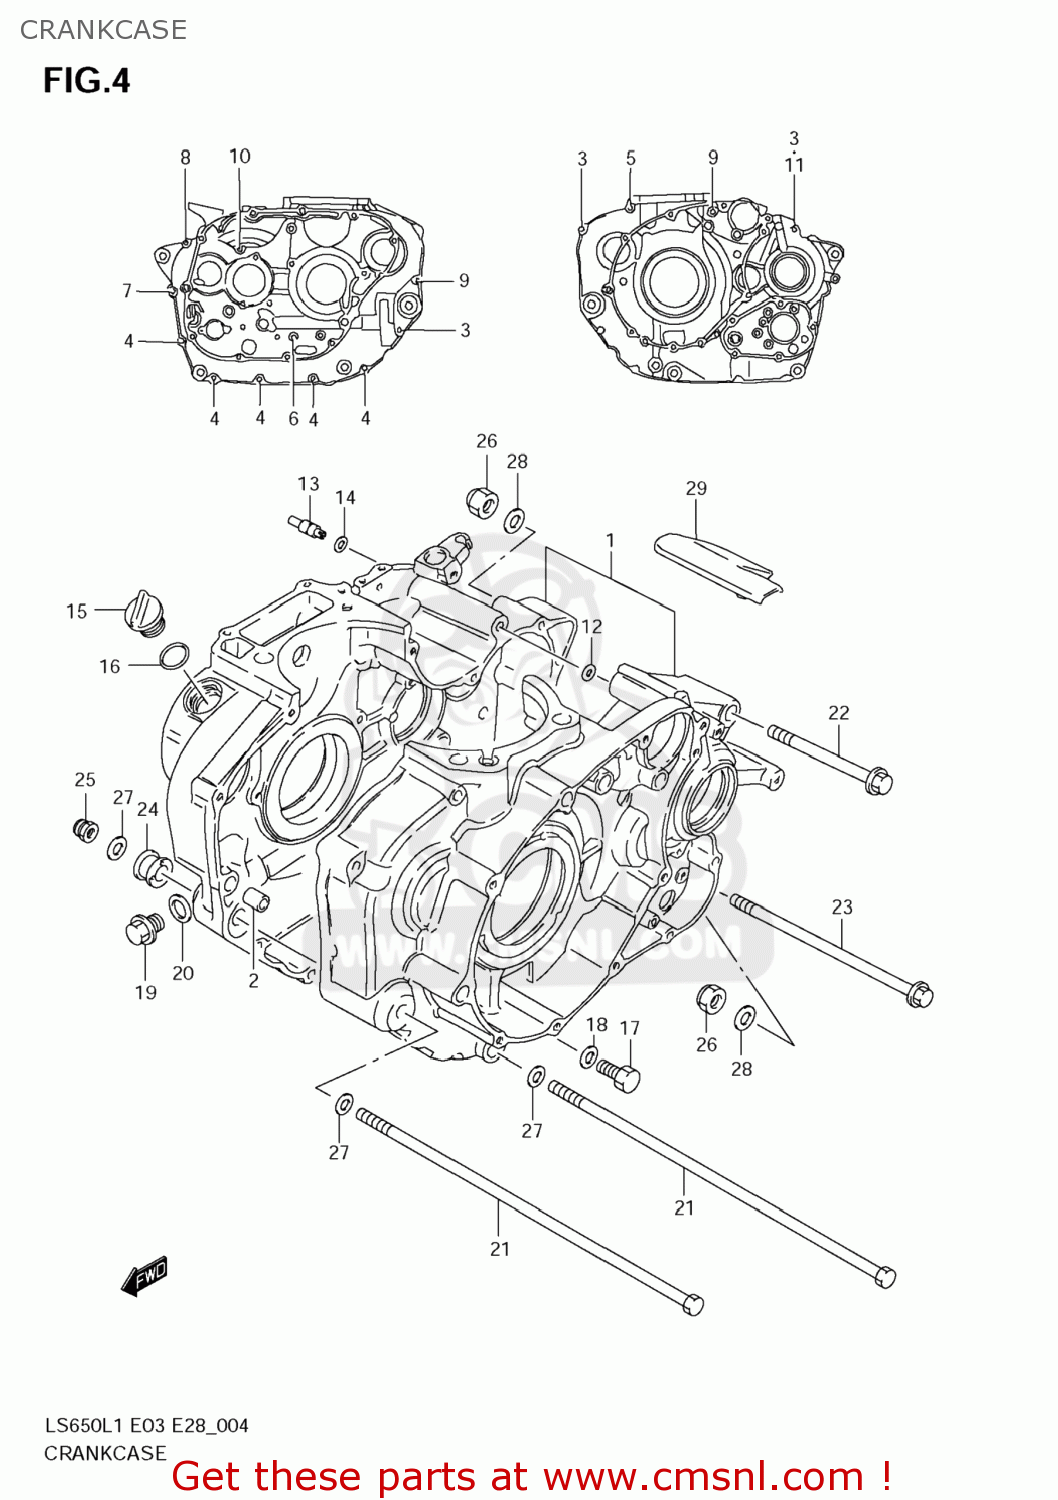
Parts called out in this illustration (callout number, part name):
1	CRANKCASE SET
2	PIN(8.4X11X20)
3	BOLT
4	BOLT
5	BOLT
6	BOLT
7	BOLT
8	BOLT
9	BOLT
10	BOLT
11	GASKET(5.8X13X1.2) (NAS)
12	O RING(D:2.4,ID:9.6)
13	JET,OIL GALLERY(18)
14	O RING(D:1.2,ID:4)
15	PLUG,ENGINE OIL FILLER
16	O RING(D:3.1,ID:16.8)
17	PLUG(12X20)
18	GASKET(12.1X16.2X3.7) (NAS)
19	PLUG(14X12)
20	GASKET(13.8X18.8X4.8) (NAS)
21	BOLT(10X323)
22	BOLT(10X105)
23	BOLT(10X180)
24	SPACER,ENGINE MOUNT(L20)
25	NUT
26	NUT
27	WASHER
28	WASHER
29	COVER,CRANKCASE START MOT
